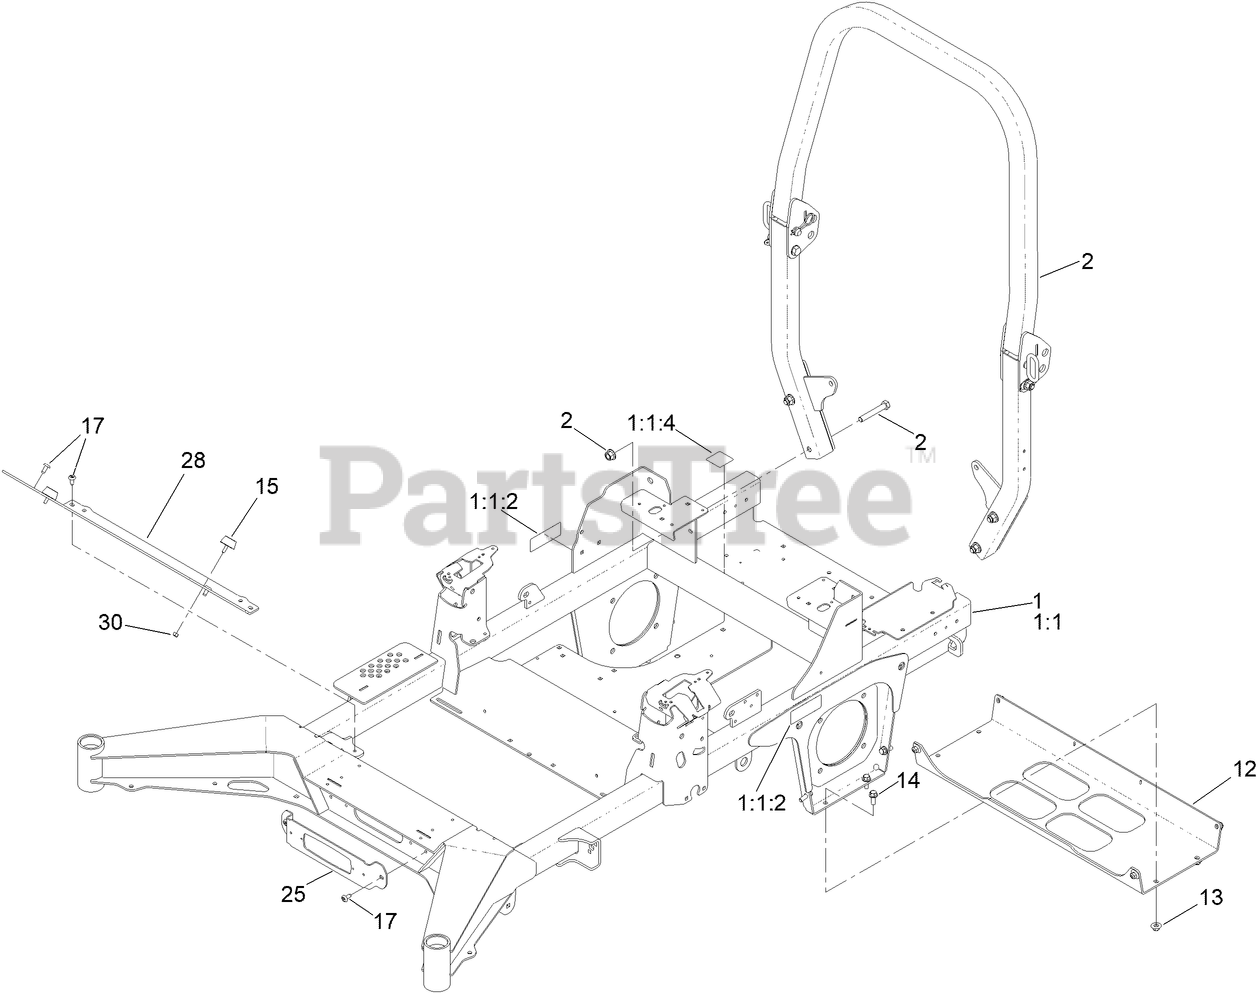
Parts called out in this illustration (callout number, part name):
1	FRAME ASM
1:1	FRAME-72 XL
1:1:2	DECAL-WARNING
1:1:4	DECAL, BELT ROUTING
2	ASM-ROPS
12	PLATE-HYDRO
13	NUT-FLANGE, NI
14	SCREW-HHF
15	BUMPER
25	BRACKET-LIGHT
28	TOEBOARD [RED]
30	NUT-LOCK, NI
